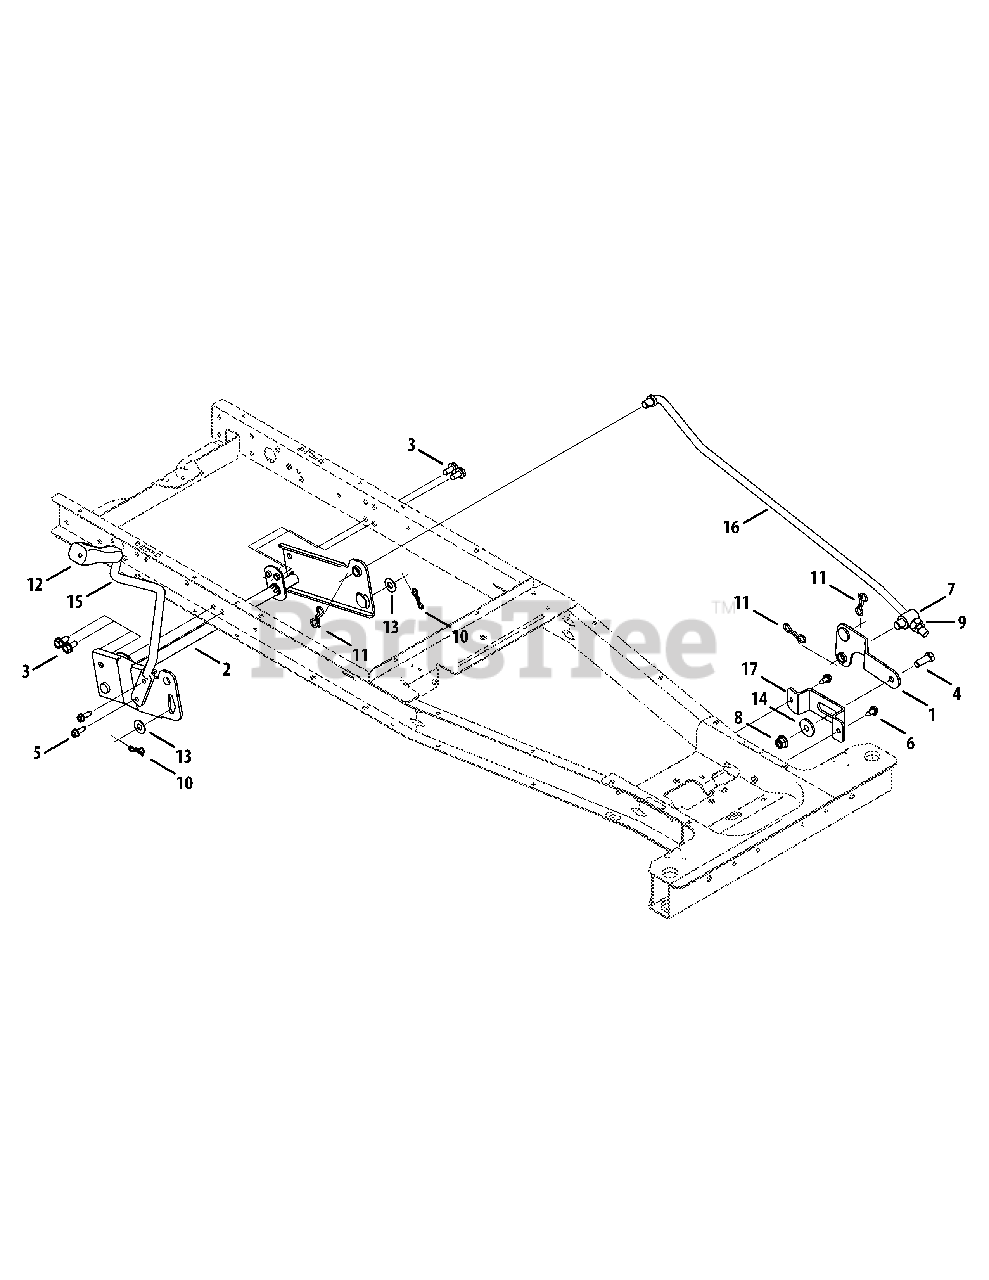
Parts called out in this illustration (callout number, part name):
1	Front Hanger Bracket Assembly
2	Lift Assembly Shaft
3	Tap Screw, 5/16-18, .750
4	Hex Head Screw, 3/8-16, 1.00
5	Tap Screw, 1/4-20, 0.750
6	Tap Screw, 1/4-20 X .625
7	Ferrule, .50 X .50
8	Flange Lock Nut, 3/8-16
9	Hex Lock Nut, 1/2-13
10	Bow-Tie Cotter Pin, 72
11	Bow-Tie Cotter Pin, 91
12	Grip Handle, 1/2
13	Flat Washer, .406 X .875 X .059
14	Shoulder Spacer, .625 ID X .169
15	Deck Lift Rod
16	Lift Link Rod
17	Front Deck Mounting Bracket
